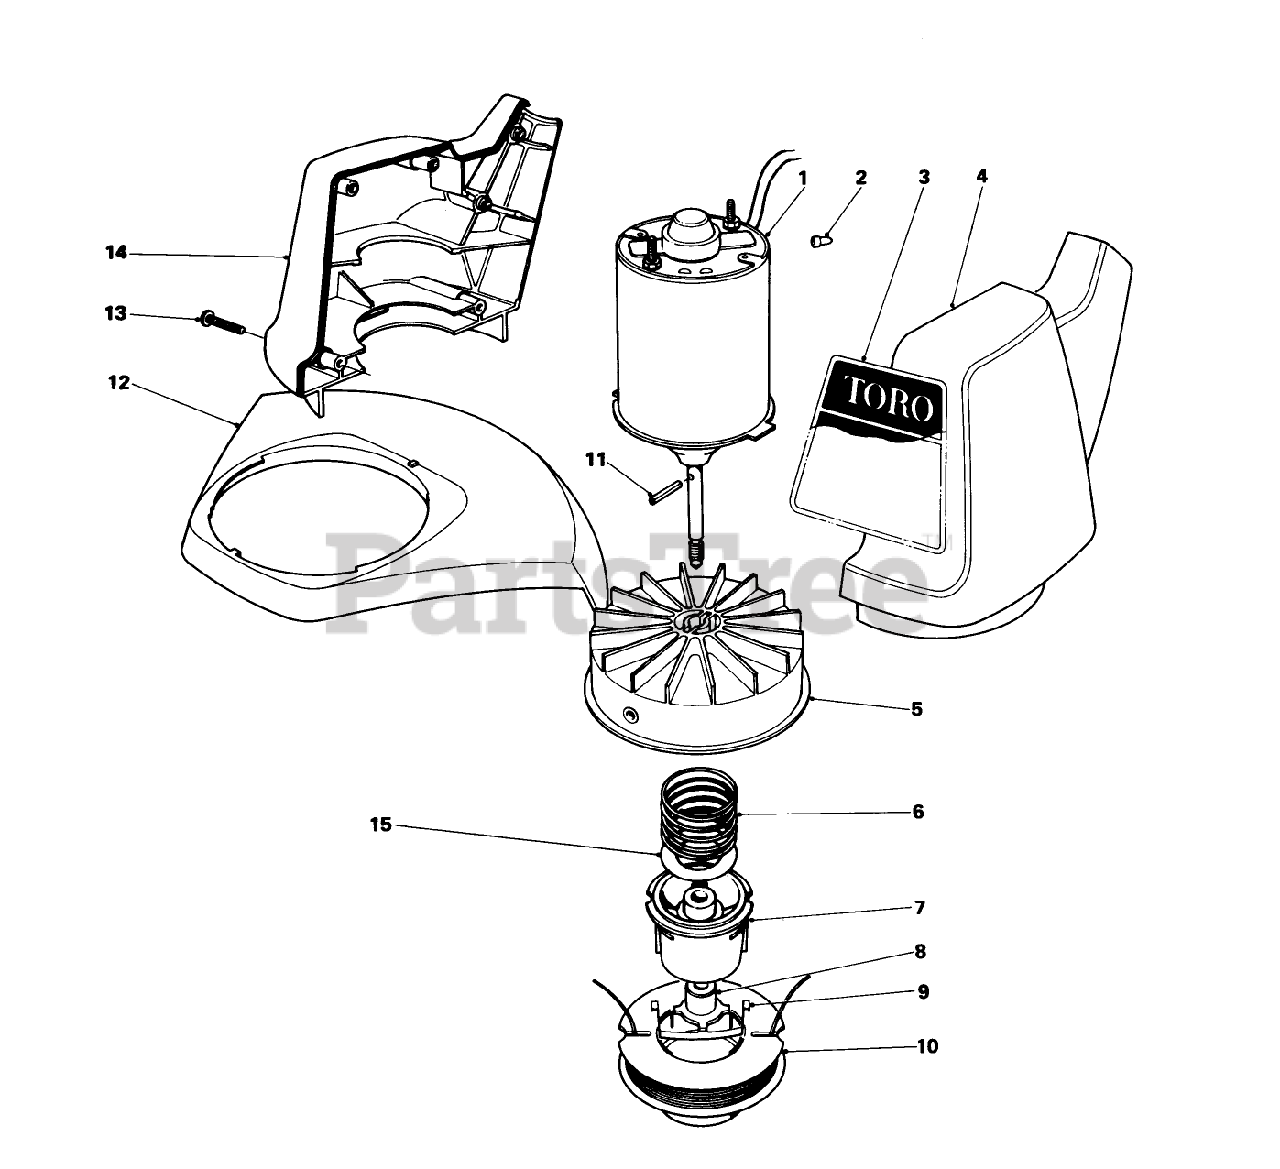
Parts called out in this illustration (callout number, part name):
6	SPRING COMPRESSION
7	SPOOL CORE
11	COIL PIN
13	SCREW-PPH
15	Washer
